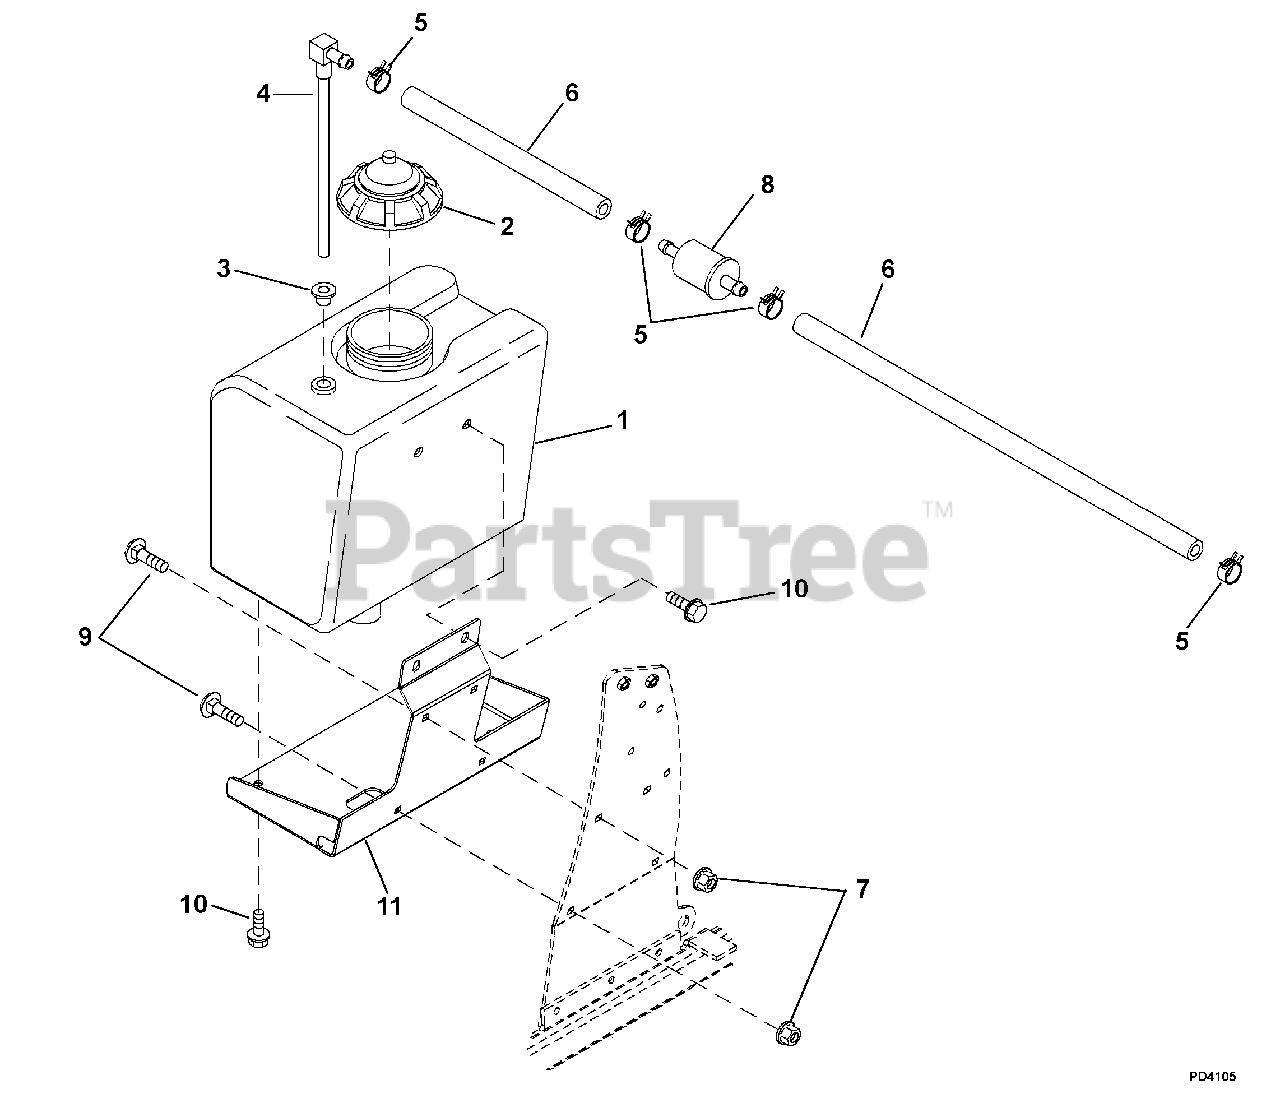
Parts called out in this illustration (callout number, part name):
1	Fuel Tank (Inclludes items 2, 3, 4)
2	Cap, Fuel
3	Grommet
4	Fuel Pickup
5	Clamp, Fuel Line
6	Hose, 10 FT Service #
7	Nut, Hex Jam .375-16
8	Filter, Fuel
9	Carriage Bolt, 3/8-16 x 1.00 Grade 5
10	Screw, Flange Hex Head JDS123 M8 x 1.25 x 16
11	Bracket, Fuel Tank Mounting
